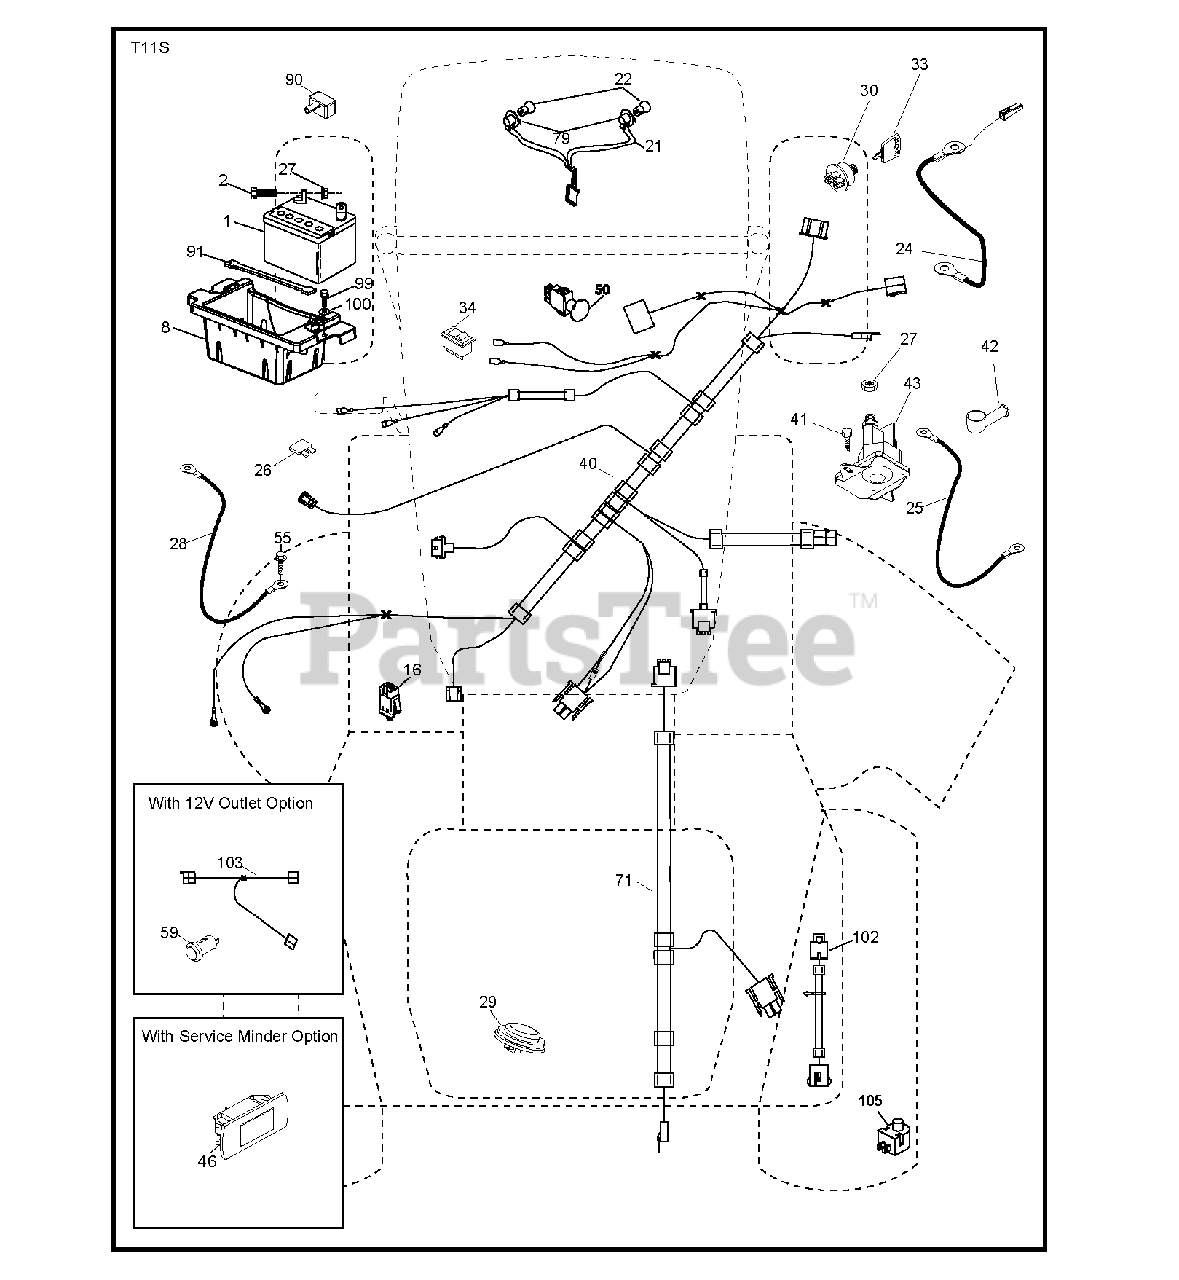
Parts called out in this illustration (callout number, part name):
1	REPL BY 532 12 38-99
8	BOX.BATTERY.MOUNT.FRONT.LT
16	SWITCH INTERLOOK PUSH-IN
21	HARNESS.LIGHT W/4152J BULBS
22	LIGHTBULB
24	CABLE.BATT.POS.WIRE.TG.DA SOL
25	CABLE.STARTER.6G.BL/RED.17.5
26	FUSE 20AMP
27	NUT
28	CABLE GROUND 6 GA 21" 90T BLK
29	SWITCH.SEAT.DELTA.OPC.
30	SWITCH.IGN.DELTA.W.LGH.ROS
33	KEY.CHAIN.BLISTER.PACK.GEN.USA
34	SWITCH LT
40	HARNESS.IGN.DASH.HUQ/P
41	SCREW
42	TERMINAL COVER
43	SOLENOID.W/BRASS.PLUNG
46	GUAGE.SRVCMNDR.HRMTR.
50	PTO SWITCH
55	SCREW 5/16"
71	HARNESS-CHASSIS SUB
79	BULB HOLDER ASM.
90	COVER.TERMINAL.BATTERY
91	STRAP, BATTERY MOUNT
99	SCREW HEXWSHR 1/4-20X3/4
102	HARNESS PIGTAIL PCH TEX ROS
105	REVERSE SWITCH
